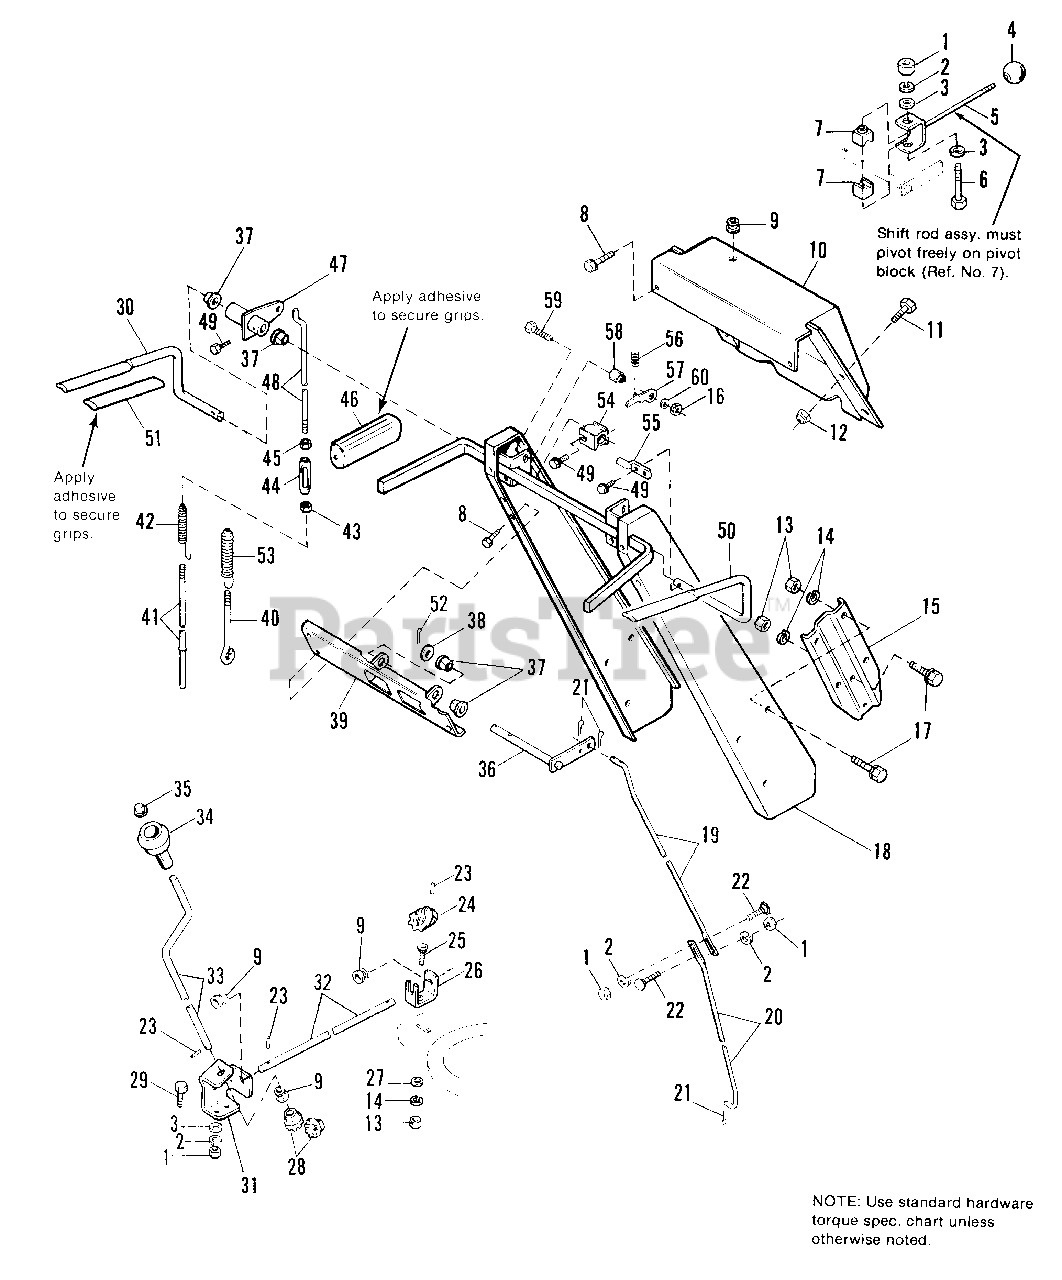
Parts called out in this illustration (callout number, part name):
1	NUT, Hex, 1/4-20
2	LOCKWASHER, 1/4
3	WASHER, Flat, 1/4
5	SHIFT ROD ASSY.
6	CAPSCREW, Hex Hd., 1/4-20 x 2-1/4
7	BLOCK, Pivot
8	SCREW, Taptite, 1/4-20 x 1/2
9	BUSHING, Plastic
10	DASH, Handle
11	CAPSCREW, Washer Hd., 1/4-20 x 3/4
12	NUT, Nylon Lock, 1/4-20
13	NUT, Hex, 5/16-18
14	LOCKWASHER, 5/16
15	BRACKET, Handle Mtg.
16	NUT, Hex Lock, 5/16-18
17	CAPSCREW, Whizlock 5/16-18 x 3/4
18	HANDLE ASSY.
19	ROD, Shift-Upper
20	ROD, Shift-Lower
21	PIN, Cotter
22	BOLT, Carriage, 1/4-20 x 3/4
23	PIN, Roll, 1/8 x 3/4
24	WORM, Chute
25	BOLT, Carriage, 5/16-18 x 3/4
26	SUPPORT, Worm
27	WASHER, Flat, 5/16
28	GEAR, Universal
29	CAPSCREW, Hex Hd., 1/4-20 x 3/4
30	HANDLE, Clutch, L.H.
31	SUPPORT, Universal Gear
32	ROD, Chute Worm
33	ROD, Chute Control
34	KNOB, Spinner
35	PALNUT
36	PIVOT ROD ASSY.
37	BUSHING, Plastic
38	WASHER
39	BRACKET, Shift Control
40	ROD, Clutch-Lower, Auger
41	ROD, Clutch-Lower, Traction
43	NUT, Hex, #10-24, R.H.
45	NUT, Hex, #10-24, L.H.
46	GRIP, Handle Bar
47	CLUTCH LEVER ASSY.
48	ROD, Clutch-Upper
49	SCREW, Taptite, #10-24 x 1
50	HANDLE, Clutch R.H.
51	GRIP, Clutch
52	PIN, Cotter, 1/8 x 1
54	GUIDE, Control
55	ROD, Control
56	SPRING
57	LATCH, Control
58	SPACER, Special
59	CAPSCREW, Hex Hd., 5/16-18 x 1-1/2
60	WASHER, Plain
